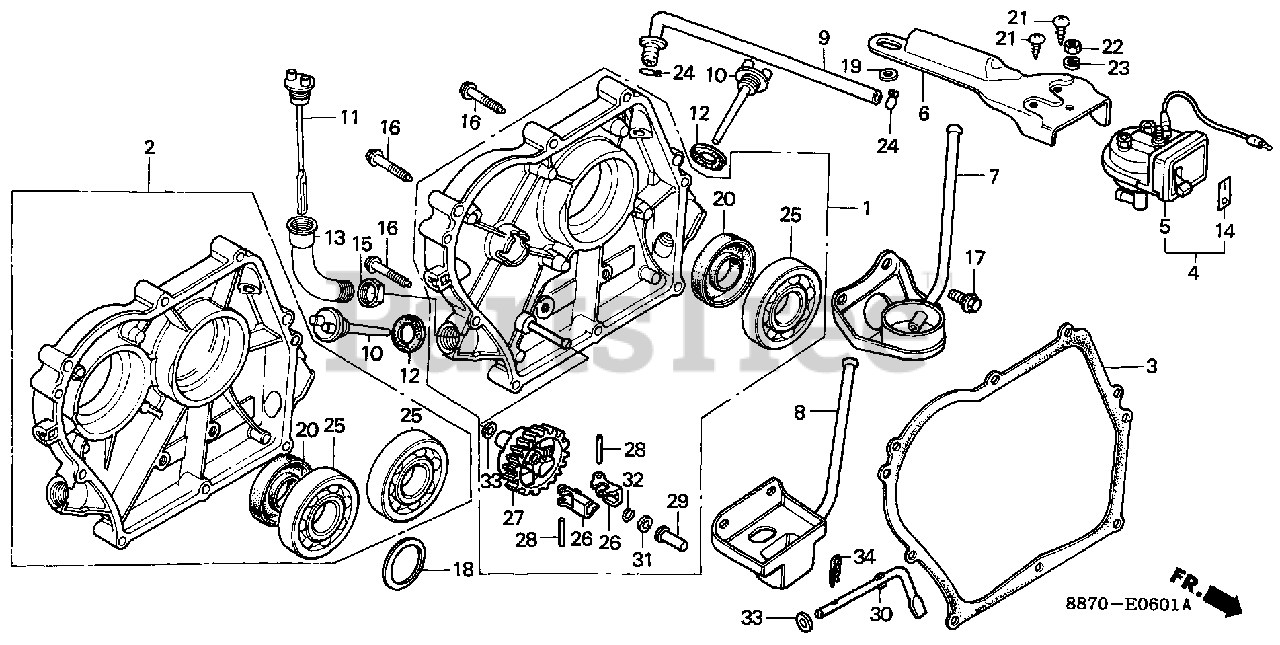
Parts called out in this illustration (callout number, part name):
1	COVER ASSY., CRANKCASE
3	GASKET, CASE COVER
5	SWITCH ASSY., OIL ALERT UNIT
6	BRACKET, OIL ALERT UNIT SWITCH
8	CUP, OIL
9	TUBE, OIL ALERT
10	CAP, OIL (YELLOW)
12	GASKET, OIL FILLER CAP
16	BOLT, FLANGE (6X32)
17	BOLT, FLANGE (6X16)
19	WASHER (18MM)
20	OIL SEAL (25X41X6)
21	SCREW, TAPPING (5X10)
22	NUT, HEX. (5MM)
23	WASHER, SPRING (5MM)
24	CLIP, TUBE (C11)
25	BEARING, RADIAL BALL (6205)
